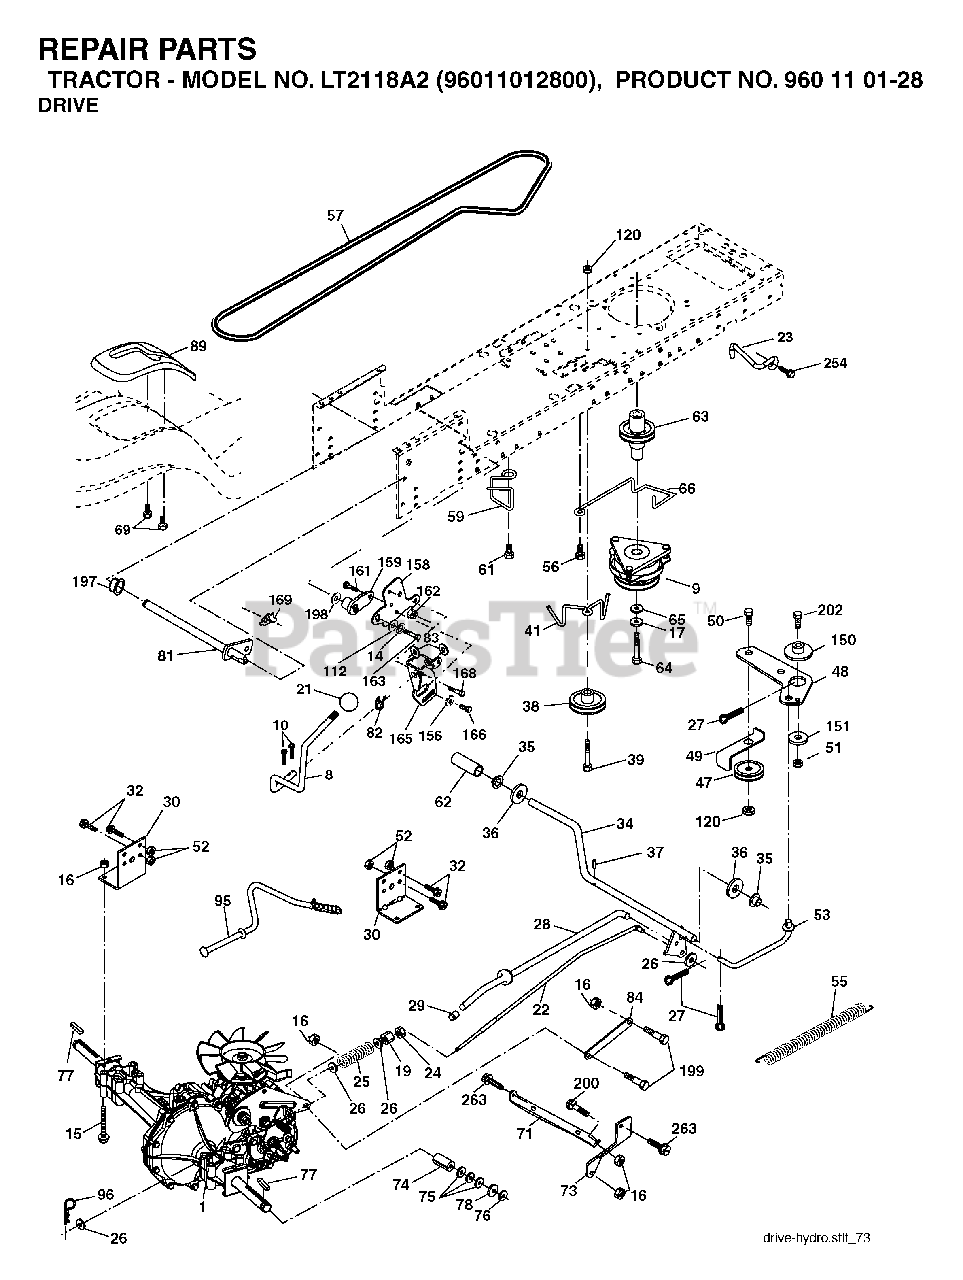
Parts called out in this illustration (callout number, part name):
8	ROD.SHIFT.FENDER.ADJ.STLT
10	PIN COTTER
14	LOCKWASHER
15	BOLT HEX 5/16-18 GR 5
16	NUT.71038.31-18.HEX.NYLOCK
19	NUT
21	PISTOL KNOB
22	ROD BRAKE HYDRO
23	BRACKET, ANTI-ROTATION
24	NUT
25	SPRING ROD LT
27	COTTER PIN
28	ROD, PARKING BRAKE
29	PLUNGER CAP
30	BRKT, TRNSXLE MNT 20"
32	BOLT
34	SHAFT, FOOT PEDAL
35	BEARING.NYLON
36	WASHER LT
37	DRIVE PIN
38	PULLEY IDLER COMPOSITE
41	KEEPER, BELT IDLER
47	IDLER PULLEY
48	BELLCRANK, CLUTCH
49	RETAIN BELT
50	BOLT.3/8-16X1.50
51	LOCKNUT
52	LOCKNUT
53	LINK.CLUTCH.7.66.2005
55	SPRING, RETURN LT
56	SCREW.3/8-16
57	DRIVE BELT, LTH & YTH TRACTORS
59	KEEPER, BELT CENTER
61	SCREW 3/8-16X.875
62	PEDAL COVER T
63	PULLEY- ENGINE
64	BOLT HEX 7/16-20X4-1/4"
65	LOCKWASHER
66	KEEPER BELT ENGINE
69	SCREW.HI-LO.CONSOLE
71	STRAP TORQUE LH HYDRO
73	STRAP TORQUE RH HYDRO
74	SPACER AXLE
76	E-RING LT
77	SQUARE KEY
81	SHAFT ASM CROSS TAPERED
82	SHIFT SPRING
83	WASHER
84	LINK TRANSAXLE
95	CONTROL ASM. BYPASS HYDRO
96	RETAINER M
112	WASHER LT
120	NUT LOCK FLG 3/8-16 UNC
150	SPACER, RETAINER
151	WASHER 12/32X2X10GA
156	WASHER.SRRTD.5/16
158	BRACKET
159	HUB.SHIFT
161	BOLT
162	NUT.CROWNLOCK.1/4
165	RP BRACKET
168	BOLT.SHOULDER.5/16-18X
169	PLATE.FASTENING.CROSS.SHAFT
197	NYLINER SNAP 5/8" ID
198	WASHER.NYL.7/8IDX.105"HYD CR
199	BOLT SHOULDER 5/16-18 UNC
200	BOLT
202	BOLT
254	SCREW 3/8-16X1
263	SCREW, 3/8-16X3/4
